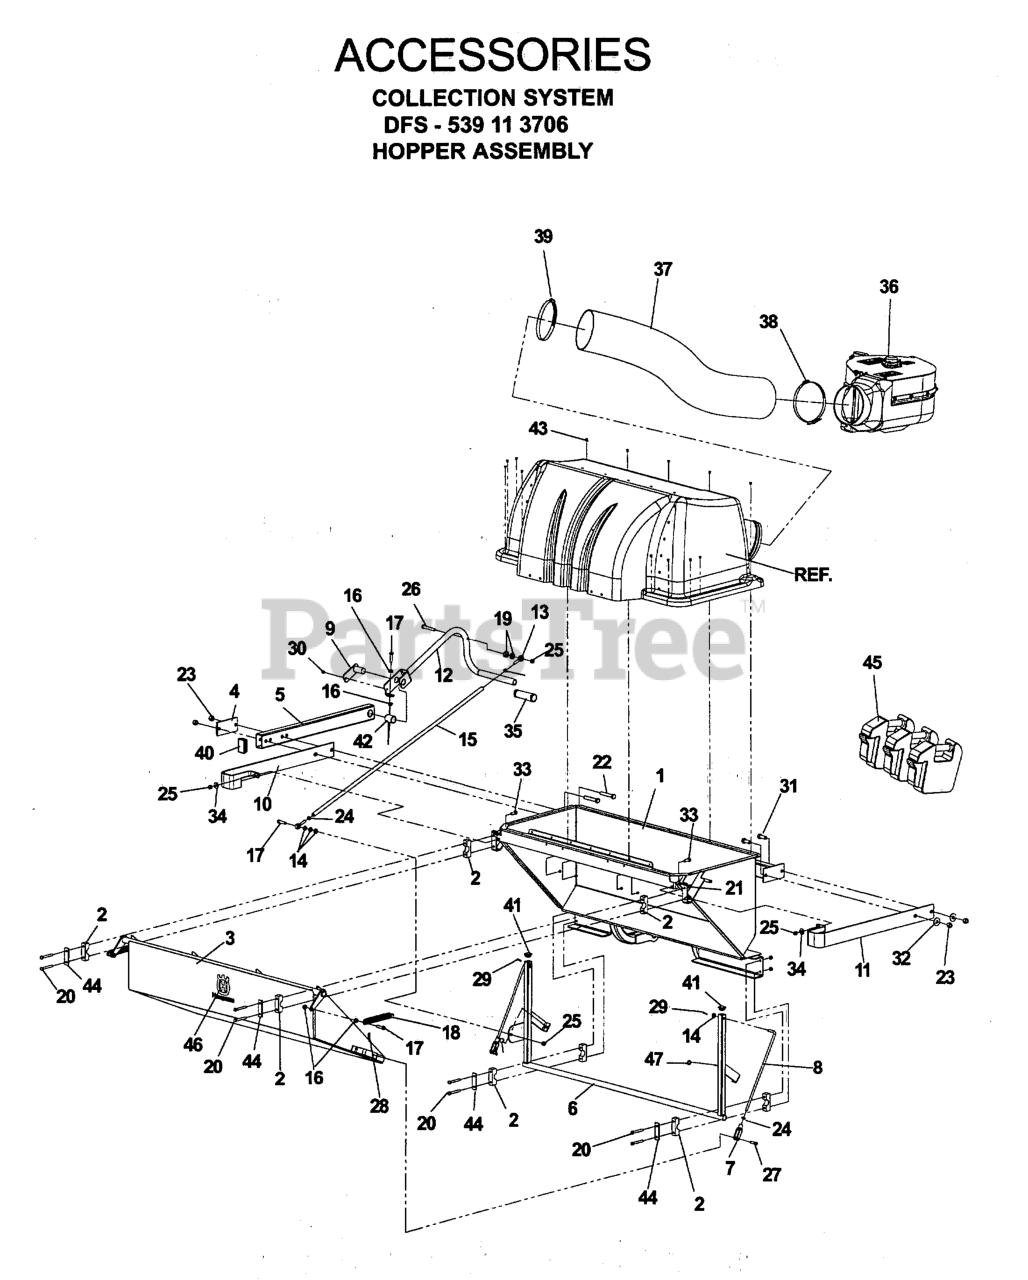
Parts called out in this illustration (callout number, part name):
1	WELDMENT - HOPPER
2	PILLOW BLOCK
3	WELDMENT - DOOR
4	PLATE - BACKING
5	TUBE - SUPPORT, HANDLE
6	WELDMENT - BELL CRANK
7	YOKE-3/8-24 PLTD
8	ROD.DOOR.COLECTION
9	WELDMENT - PIN, PIVOT
10	GUARD - L.H.
11	GUARD - R.H.
12	WELDMENT, HANDLE
13	ROD END - 3/8-24 RH
14	WASHER 3/8 SAE FLAT
15	TUBE - THREADED
16	NUT 3/8C WHIZ
17	HCS 3/8C X 1 1/2
18	SPRING BAGGER
20	BOLT 5/16C X 2 1/2
21	NUT 5/16 NYLOC
22	SCREW, 1/2C X 3 HEX CAP
23	NUT 1/2-13 HEX NYLOC ZD
24	NUT 3/8-24 JAM
25	NUT 3/8-16 NYLOC
26	HEX SCREW 3/8-20 X 2.75
27	PIN CLEVIS, 3/8 X 1 1/4
28	HAIRPIN #2
29	RP_COTTER PIN 1/8 X 3/4
30	HWST 1/4C X 3/8
31	HCS 1/2-13 X 1-1/4
32	WASH USS FLAT 1/2
33	HCS 3/8-16X1.GRD.5.ZD
34	WASHER 3/8 FLAT
35	IMPELLER KIT, 3.5/5HP
36	BLOWER ASSEMBLY
37	HOSE 7 X 58 CLEAR
38	OVER CTR BAND
39	HOSE CLAMP 4-1/8 TO 7"
40	PLUG - RETANGULAR TUBING
41	PLUG - SQUARE TUBE
42	BUSHING - BRONZE, 1.0"
43	RIVERT, 3/16, STAVEX
44	REINFORCEMENT BAR
45	FRT WEIGHT CAST PZ DFS
46	DECAL, CROWN H 5-1/4 SILVER
47	GROMMET, BUMPER
